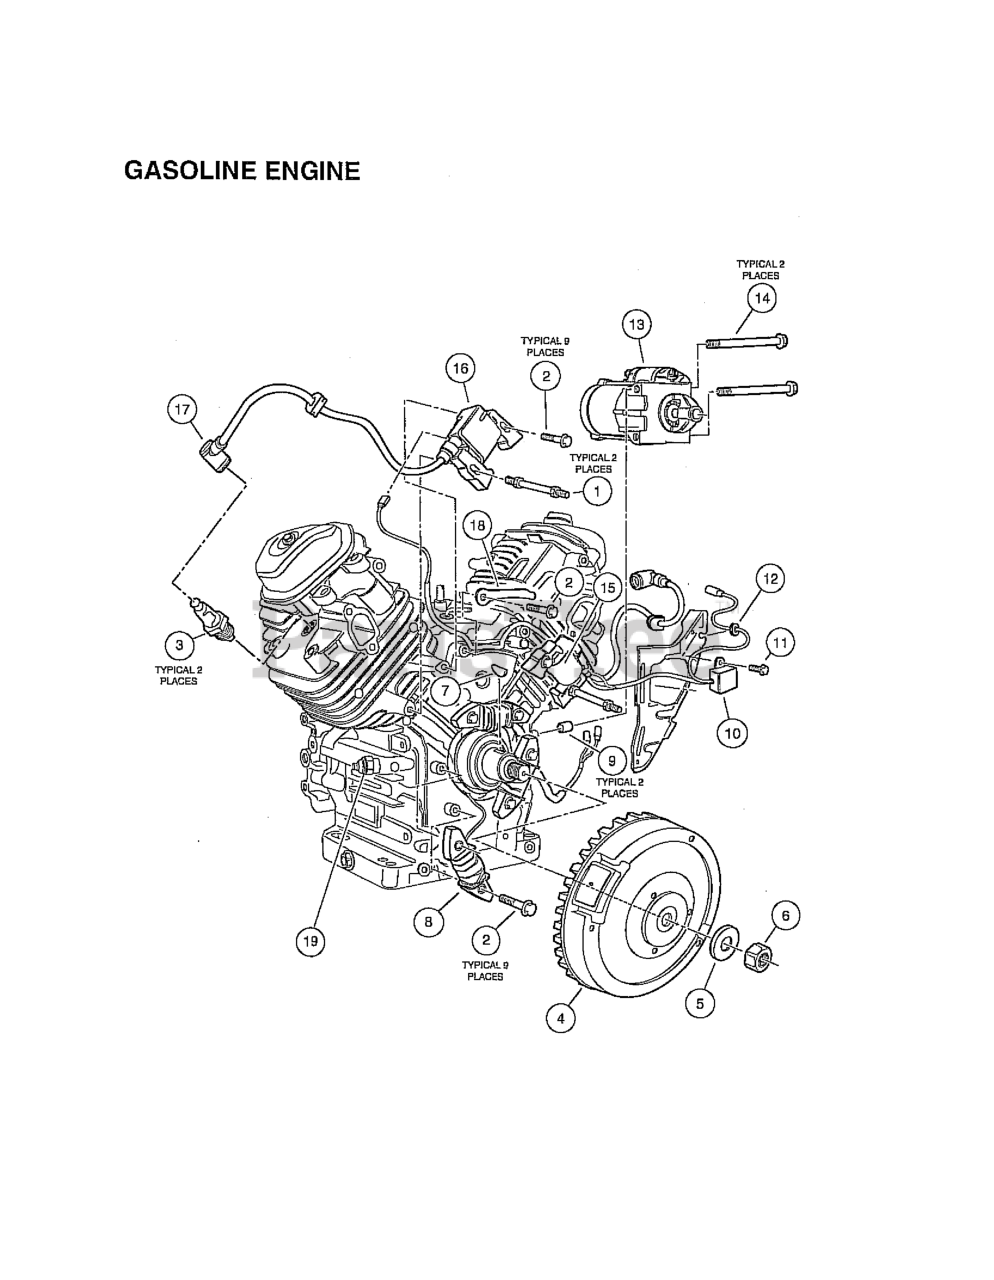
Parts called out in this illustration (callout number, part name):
1	STUD, ENGINE
2	BOLT, FLANGE, M6 X 1 X 32
3	SPARK PLUG, BPR2ES,NGK
5	WASHER, M20
6	NUT, FLANGE, M20
7	KEY, SPECIAL WOODRUFF, 25 X 18
8	COIL ASSY, CHARGE, 12V/20A
9	PIN, DOWEL, 10 X 12
10	DIODE ASSY, ENGINE STOP
11	BOLT, FLANGE, M6 X 1 X 8
12	GROMMET, TOOL
13	MOTOR ASSY, STARTER
14	BOLT, FLANGE, M8 X 1.25 X 110
15	COIL ASSY, R, IGNITION
16	COIL ASSY, L, IGNITION
18	CLAMP, WIRE
